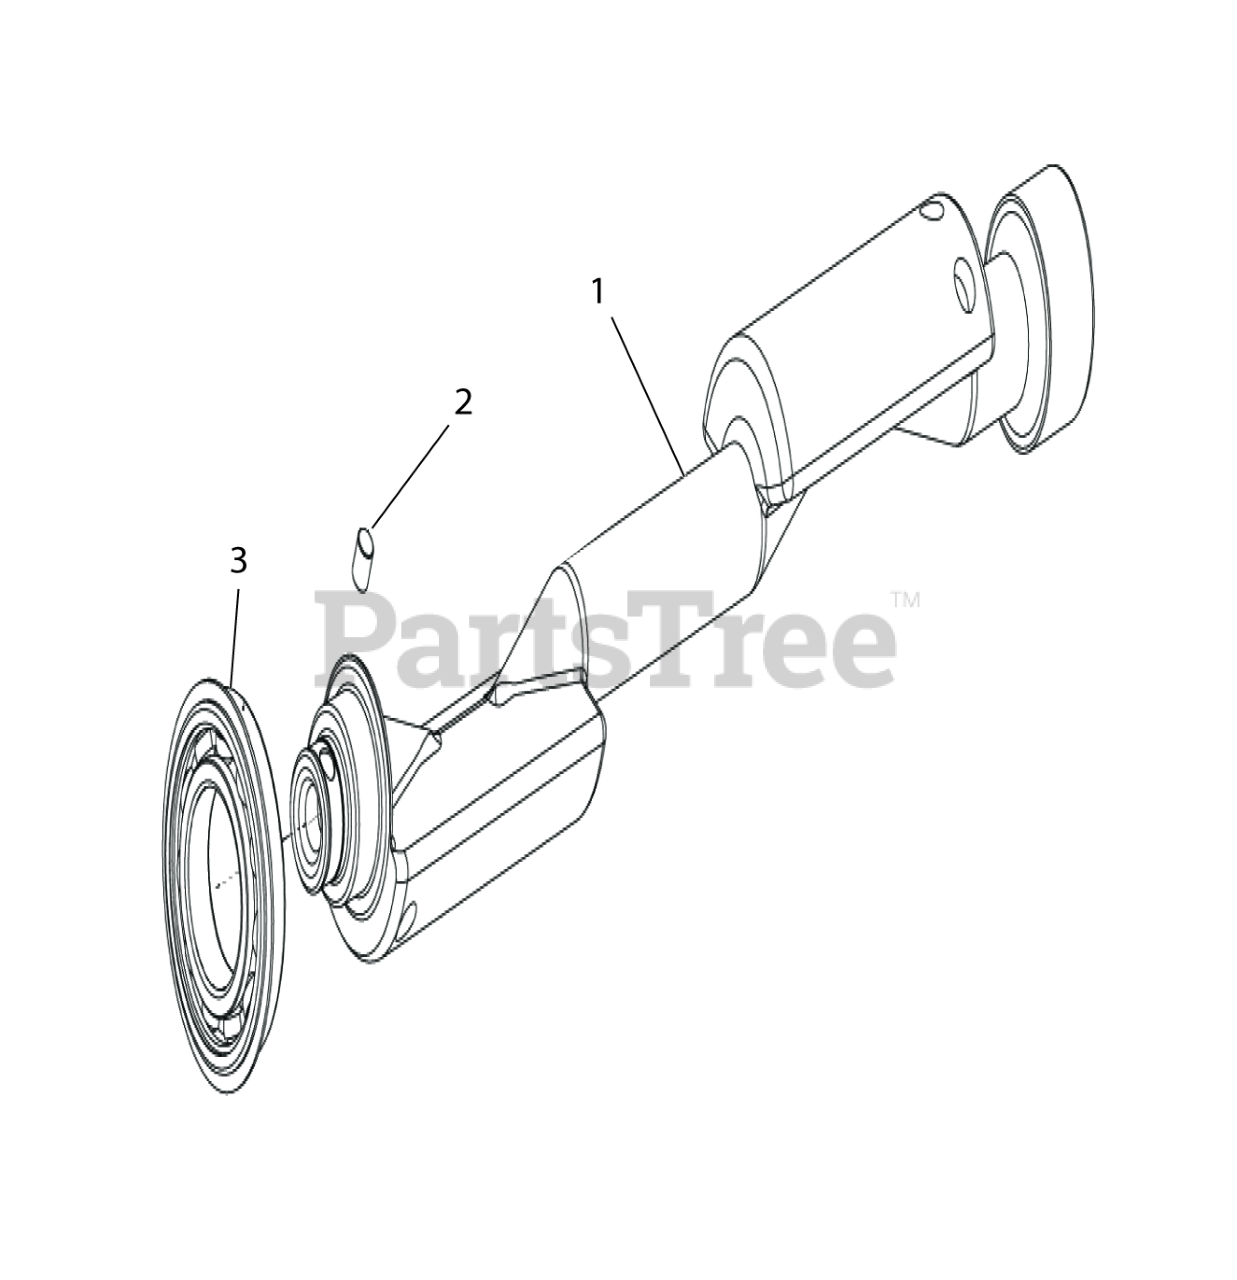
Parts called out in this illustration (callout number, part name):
1	*SHAFT, Balancer
2	*PIN, Balancer Shaft
3	*BEARING, Balance Shaft
